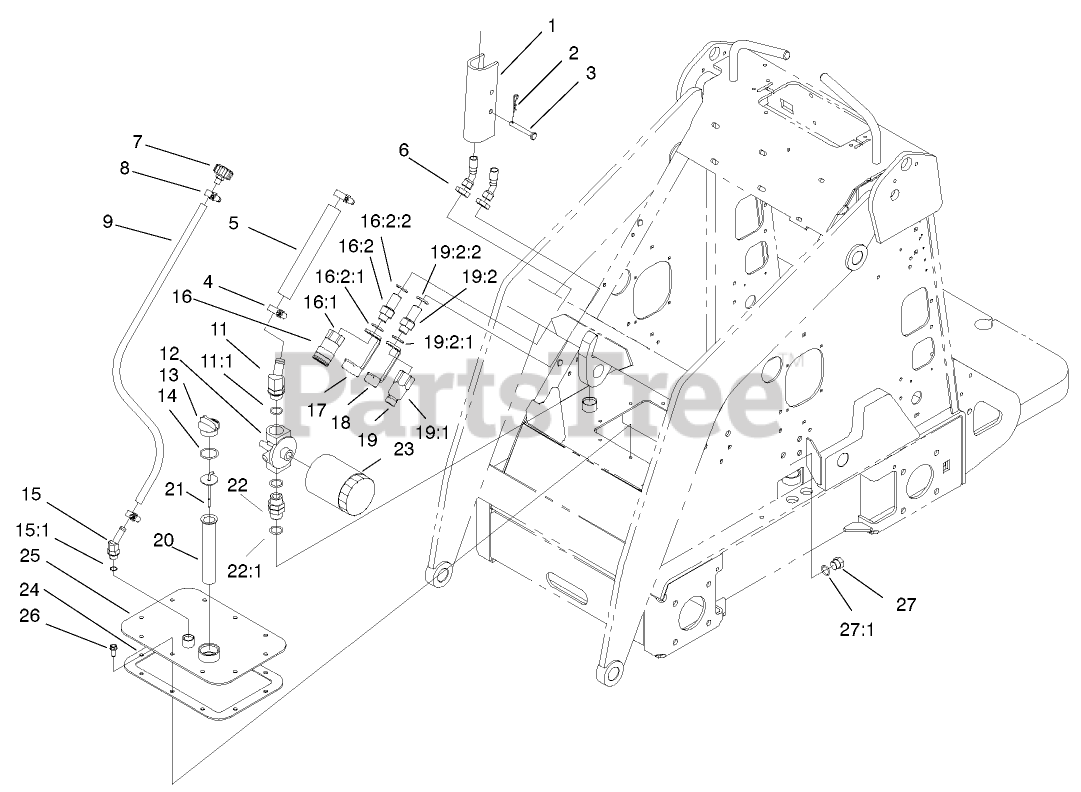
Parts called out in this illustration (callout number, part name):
1	LOCK-CYLINDER
2	PIN-HAIR
3	PIN-CLEVIS
4	CLAMP-HOSE
5	HOSE-SUCTION, HYD
6	NUT-LOCK, BULKHEAD
7	BREATHER
8	CLAMP-HOSE
9	HOSE-VENT
11	ELBOW-45 DEG
11:1	O-RING
12	HEAD-FILTER
13	PLUG-PLASTIC
14	O-RING
15	FITTING-HYD, 45 DEG
15:1	O-RING
16	BULKHEAD COUPLER ASM
16:1	COUPLER-FACE, FLUSH
16:2	FITTING-ADAPTER, BULKHEAD
16:2:1	O-RING
16:2:2	O-RING
17	CAP-DUST, NIPPLE
18	CAP-DUST, COUPLER
19	BULKHEAD NIPPLE ASM
19:1	NIPPLE-FACE, FLUSH
19:2	FITTING-ADAPTER, BULKHEAD
19:2:1	O-RING
19:2:2	O-RING
20	FILTER-SCREEN
21	DIPSTICK-OIL
22	FITTING-THREAD, STRAIGHT
22:1	O-RING
23	FILTER-OIL, TRANSMISSION
24	GASKET-COVER
26	SCREW
27	PLUG-HEX
27:1	O-RING
